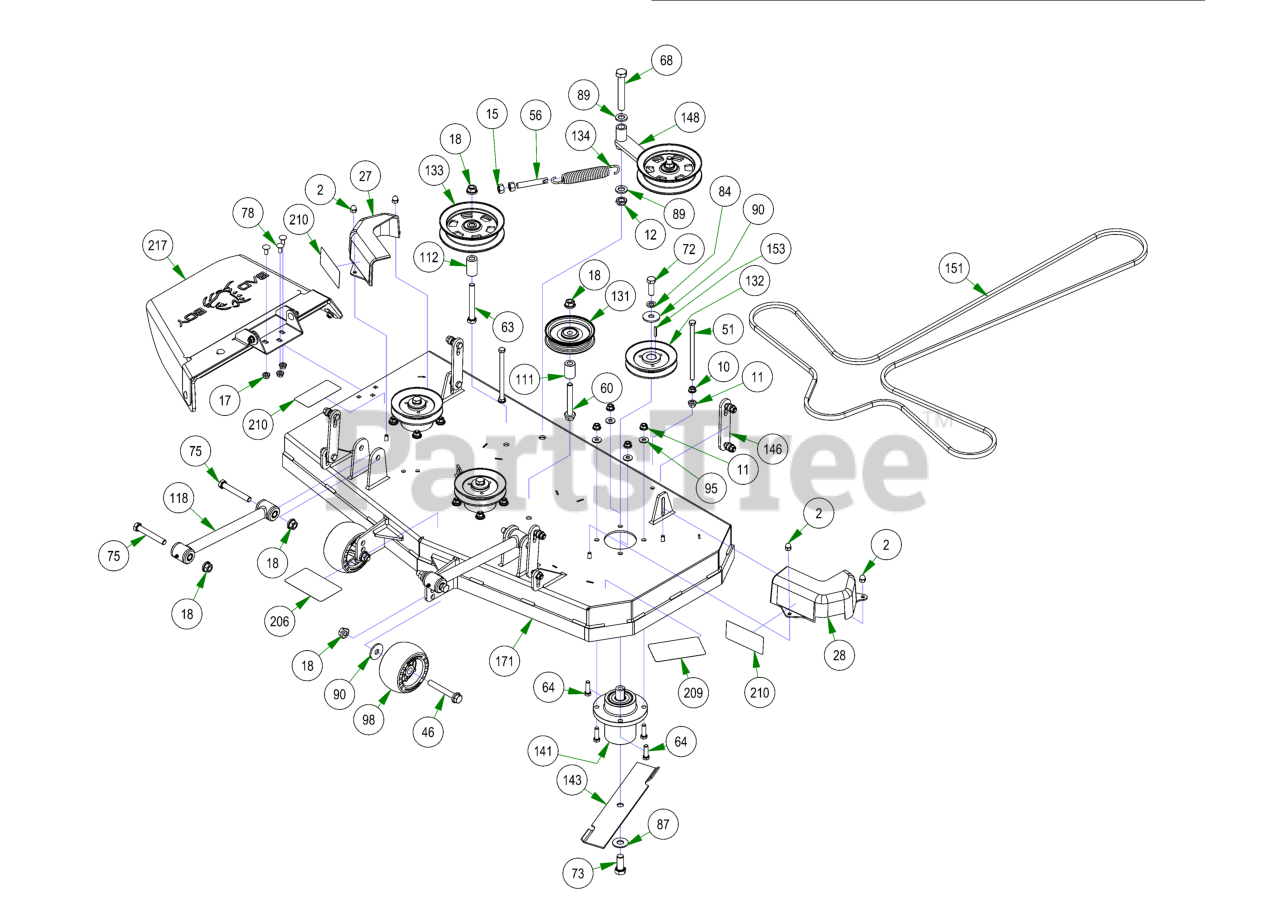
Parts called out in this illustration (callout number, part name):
2	5/16-18 ACORN NUT HIGH-CROWN ZC
10	3/8-16 HEX SERRATED FLANGE NUT HARD/ZINC
11	3/8-16 NYLON INSERT FLANGE LOCKNUT (GR.F) ZINC
12	5/8-11 NYLON INSERT JAM LOCKNUT ZINC
15	1/2-13 HEX NUT ZINC
17	5/16-18 NYLON INSERT FLANGE LOCKNUT ZINC
18	1/2-13 NYLON INSERT FLANGE LOCKNUT ZINC
27	pulley cover chute side
28	pulley cover non-chute side
46	1/2-13 X 90MM HEX FLANGE BOLT W/SHOULDER (GR.8) ZINC
51	3/8-16 X 6.5 HEX CAP SCREW (GR.5) ZINC
56	All Thread
60	1/2-13 X 3-1/2 HEX FLANGE BOLT (GR.8) ZINC
63	1/2-13 X 4 HEX CAP SCREW (GR.8) ZINC YELLOW
64	3/8-16 X 1-1/4 HEX CAP SCREW (GR.5) ZINC
68	5/8-11 X 4 HEX CAP SCREW (GR.8) ZINC YELLOW
72	1/2-20 X 1-1/2 HEX CAP SCREW (GR.5) ZINC
73	5/8-18 X 1-1/2 HEX CAP SCREW (GR.8) ZINC YELLOW
75	1/2-13 X 3-1/2 HEX CAP SCREW (GR.5) ZINC
78	5/16-18 x 3/4 Carriage Bolt
84	1/2 SPLIT LOCKWASHER (GR.8) ZINC/YELLOW
87	5/8 USS FLAT WASHER (1-3/4" OD) GR.8 ZINC YELLOW
89	.635 ID X 1.120 OD X .140 THICK FLAT WASHER NYLON
90	1/2 BELLEVILLE WASHER (1-5/8 OD X .140 THK) ZINC
95	5/16 USS FLAT WASHER (7/8 OD) ZINC
98	Deck Wheel
111	.502 ID X .750 OD X 1.500 Long Spacer
112	1 3/4" Pulley Spacer
118	Hybrid Turnbuckle/Deck Locator
131	4 3/4" Idler Pulley
132	42" MZ Spindle Pulley
133	5-3/4 Idler Pulley
134	Deck Idler Spring
141	Spindle Assembly-MZ
143	MZ 42 Blade
146	Deck Hanger Assembly
148	2017 MZ/ZT Deck Idler Assembly
151	2023 42" Deck Belt
153	3/16 X 1 SQ MACHINERY KEY 1018 STL ZINC
171	2023 42" x 4" Deck
206	2017 MZ Magnum 48"/42" Deck Route Decal
209	2018 42" MZ/Comp Out Deck Decal
210	Danger Decal-Spindle/Discharge
217	MZ Discharge Chute Assembly
